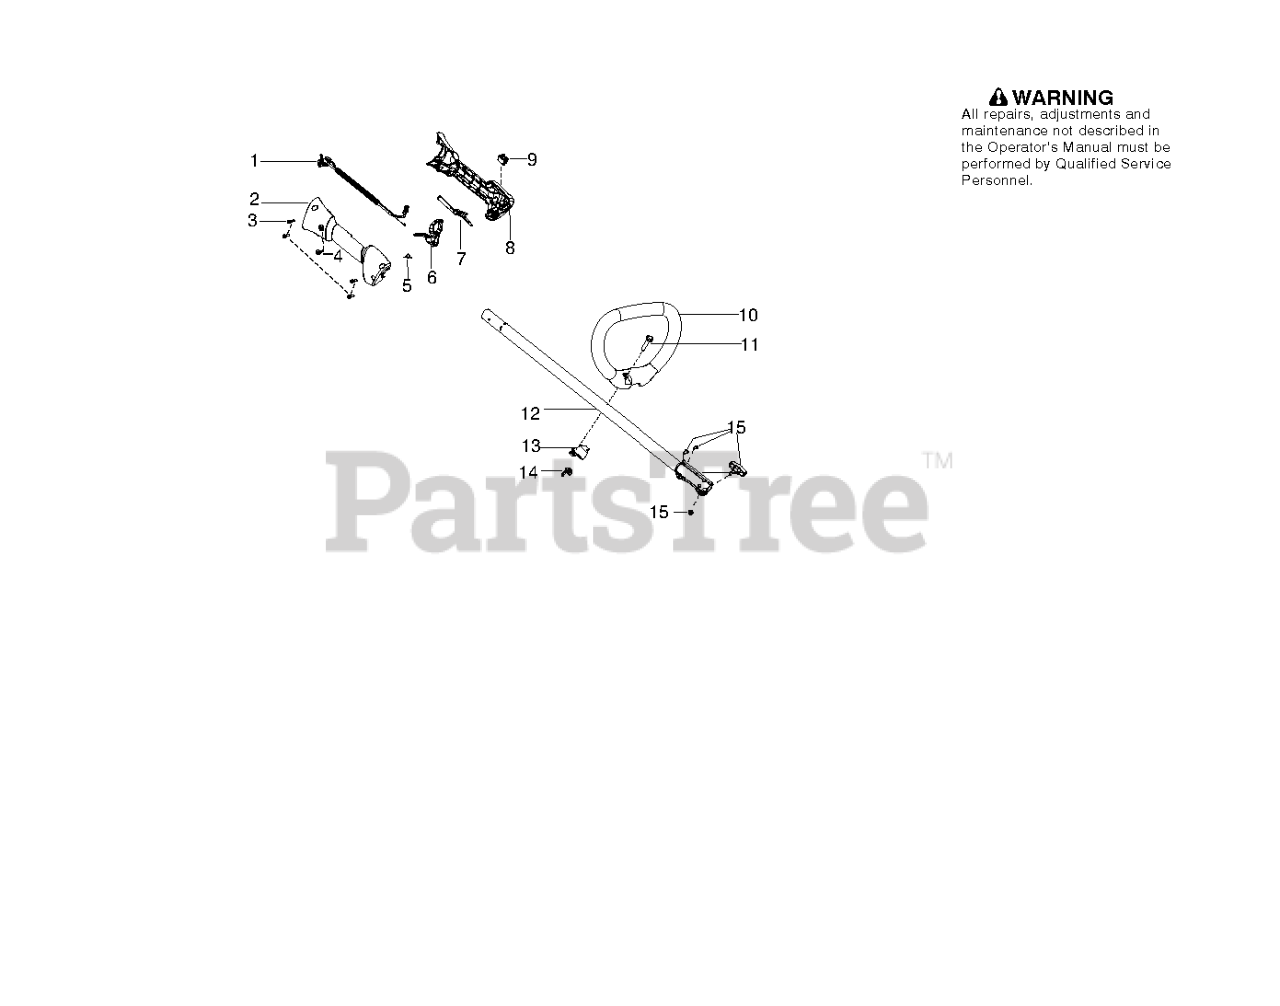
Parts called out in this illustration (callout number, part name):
1	ASSY CABLE / WIRE HARNESS
2	HSG THROTTLE RIGHT HVA
3	SCREW M4 X 1.75 PT 16MM
4	SCREW-10-14 X 1/2 PLASTITE
5	SPRING TRIGGER
6	TRIGGER THROTTLE HVA ORANGE
7	THROTTLE LOCKOUT HVA ORANGE
8	HSG THROTTLE LEFT HVA
9	SWITCH
11	BOLT, TYPE 2
12	KIT UPPER SHAFT SILVER
13	CLAMP ASSIST HANDLE
14	NUT-"D" HANDLE
15	KIT UPPER SHAFT SILVER
